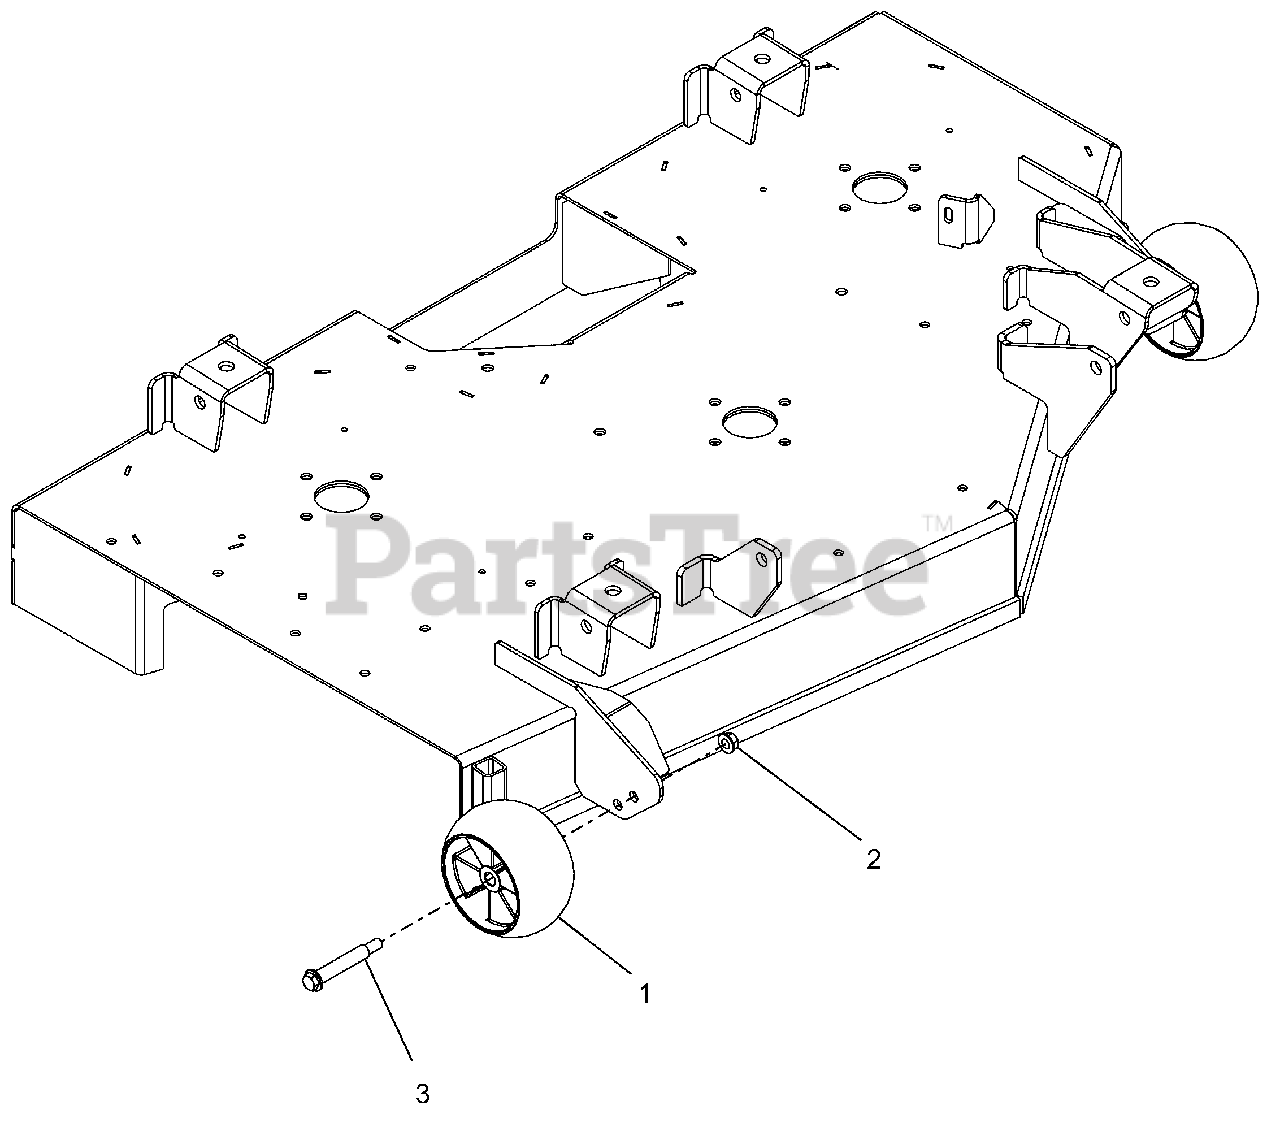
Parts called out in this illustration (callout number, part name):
1	ANTI-SCALP WHEEL - 5X OS
2	NUT-LK-CTR-FLG .375-16 GF ZCC
3	BLT-SHLDR .38-16X2.50 HWH G5
